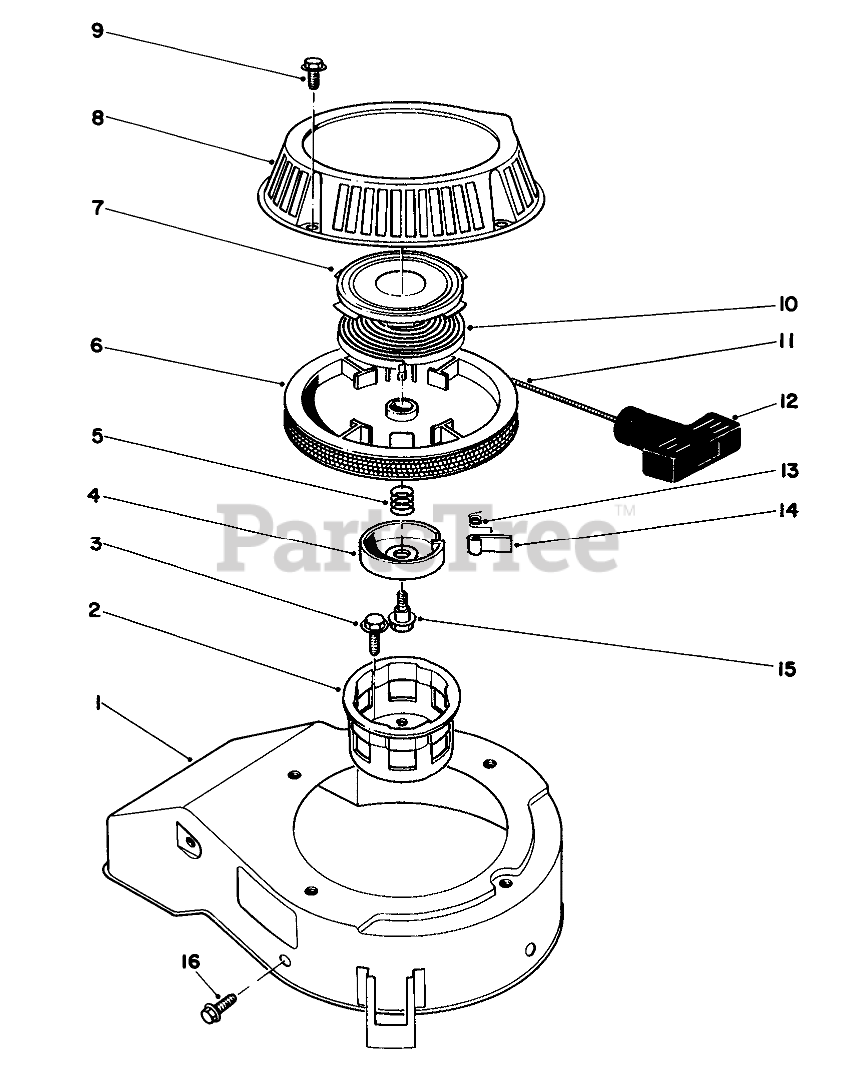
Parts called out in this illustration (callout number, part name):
1	COVER
2	CUP - STARTER
4	RETAINER
5	SPRING
7	Retainer-Recoil Spring
9	SCREW-HHF
10	Spring-Recoil
11	ROPE-STARTER
12	HANDLE-RECOIL
13	SPRING
